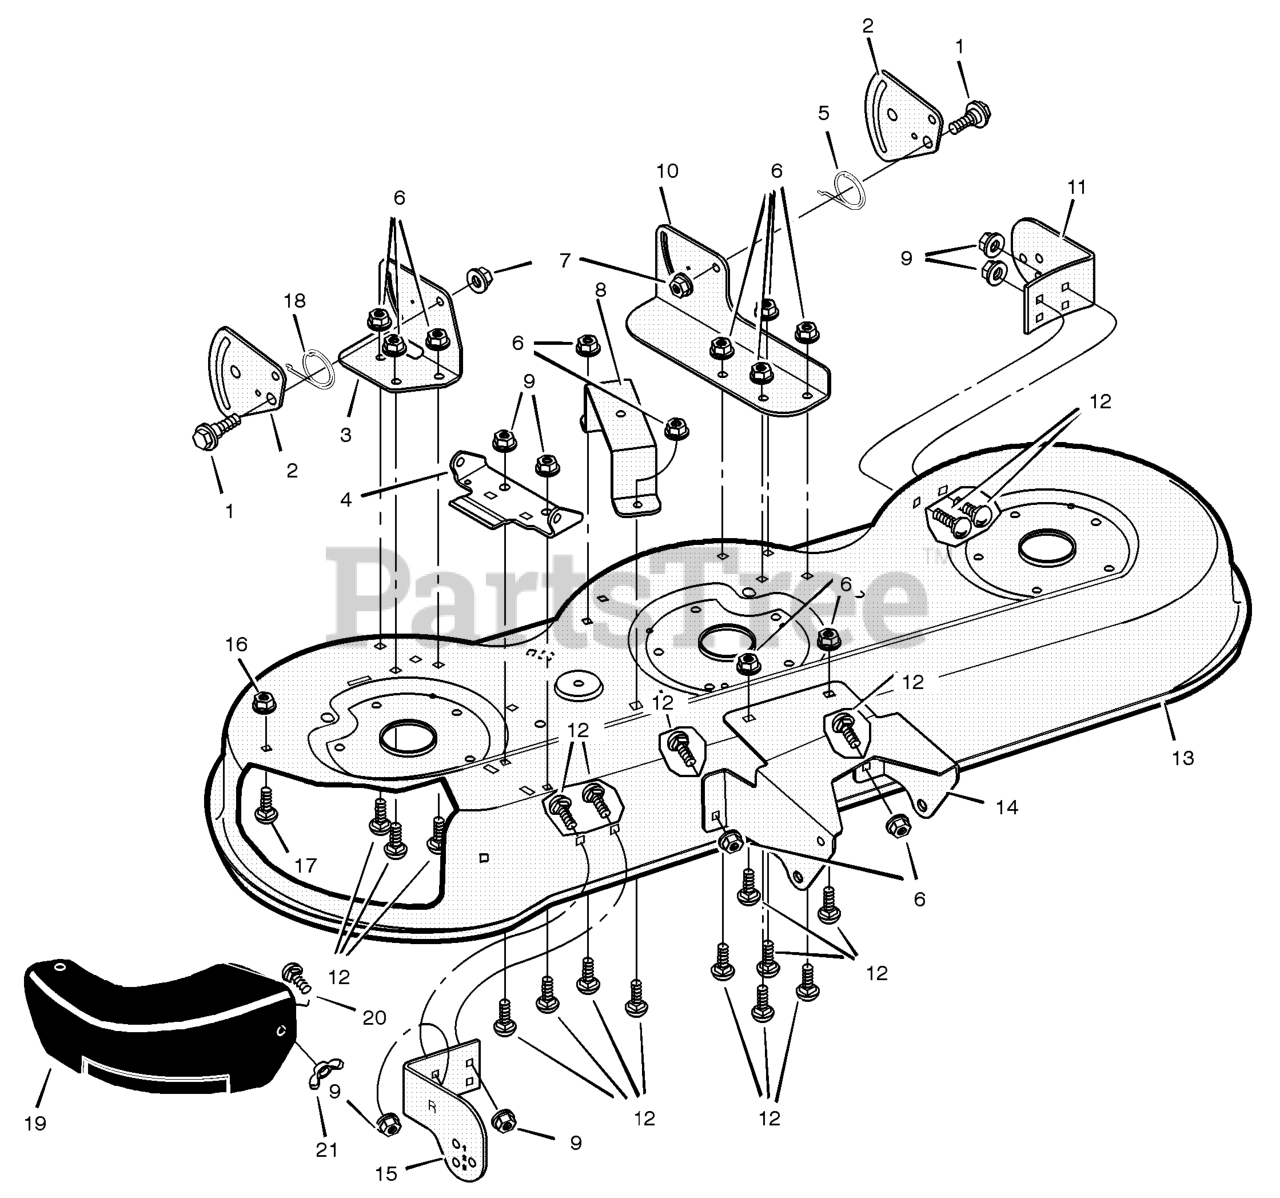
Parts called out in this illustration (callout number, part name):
1	Bolt, Shoulder
2	Plate, Suspension
3	Bracket, Right Rear
4	Bracket, Hinge
5	Spring, Left
6	Nut, Flange
7	Nut, Flange
8	Bracket, Bell Crank
9	Nut, Flange
10	Bracket, Left Lifter
11	Bracket, Left Gauge Wheel
12	Bolt, Carriage
13	Housing, Blade
14	Bracket, Front Deck
15	Bracket, Right Gauge Wheel
16	Retainer
17	Bolt, Carriage
18	Spring, Right
19	Cover, Mulcher
20	Bolt, Carriage
21	Wingnut
